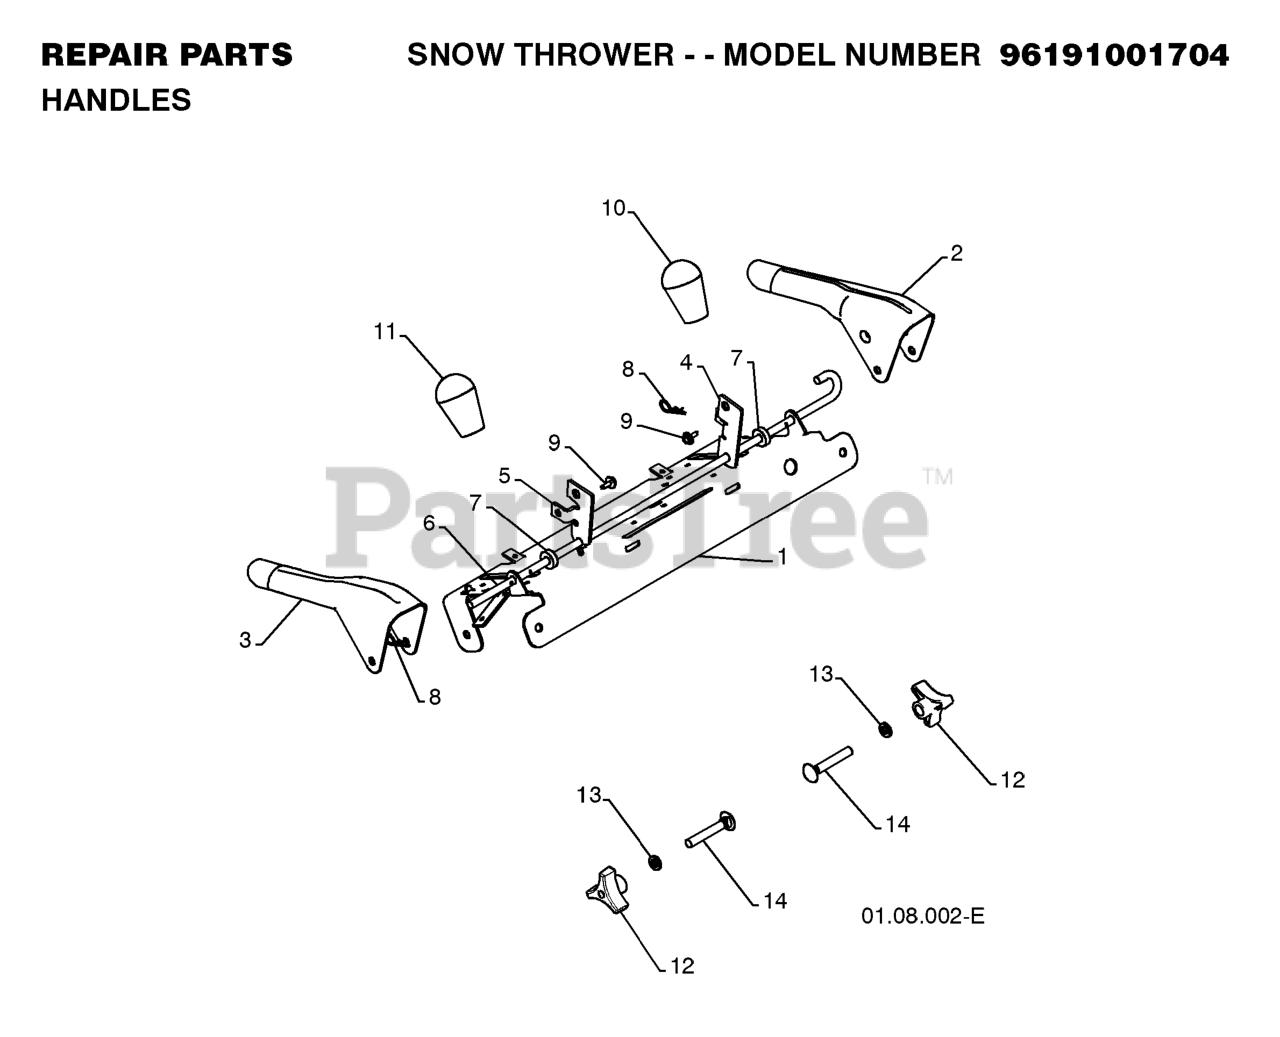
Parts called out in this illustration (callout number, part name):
1	ROD.ASM.IMPELLER
2	ROD.ASM.TRACTION
3	ROD, UPPER SPEED CONTROL
4	ROD, LOWER SPEED CONTROL.SNOW
5	SLEEVE, SPRING
6	SPRING, AUGER CONTROL
7	SPRING, TRACTION DRIVE
8	BOLT
9	NUT.FLANGE.5/16
10	SPRING RETAINER
11	ROD.CLUTCH.YELLOW.ZINC(VT)
12	PLATE.REAR.SNOW.PNT.ORANGE
13	BRACKET.SHIFTER.PLATE.BZP
14	BRACKET.CLUTCH.PLATE.BZP
15	PLATE.CLUTCH.BZP
16	PLATE.SHIFTER.BZP
17	Screw 5/16-18 x 1/2 Hex, Self Tapping 5/16-18 x 1/2
18	BOLT.SHOULDER.3/X.25
19	NUT.HEX.FLANGE.1/4
